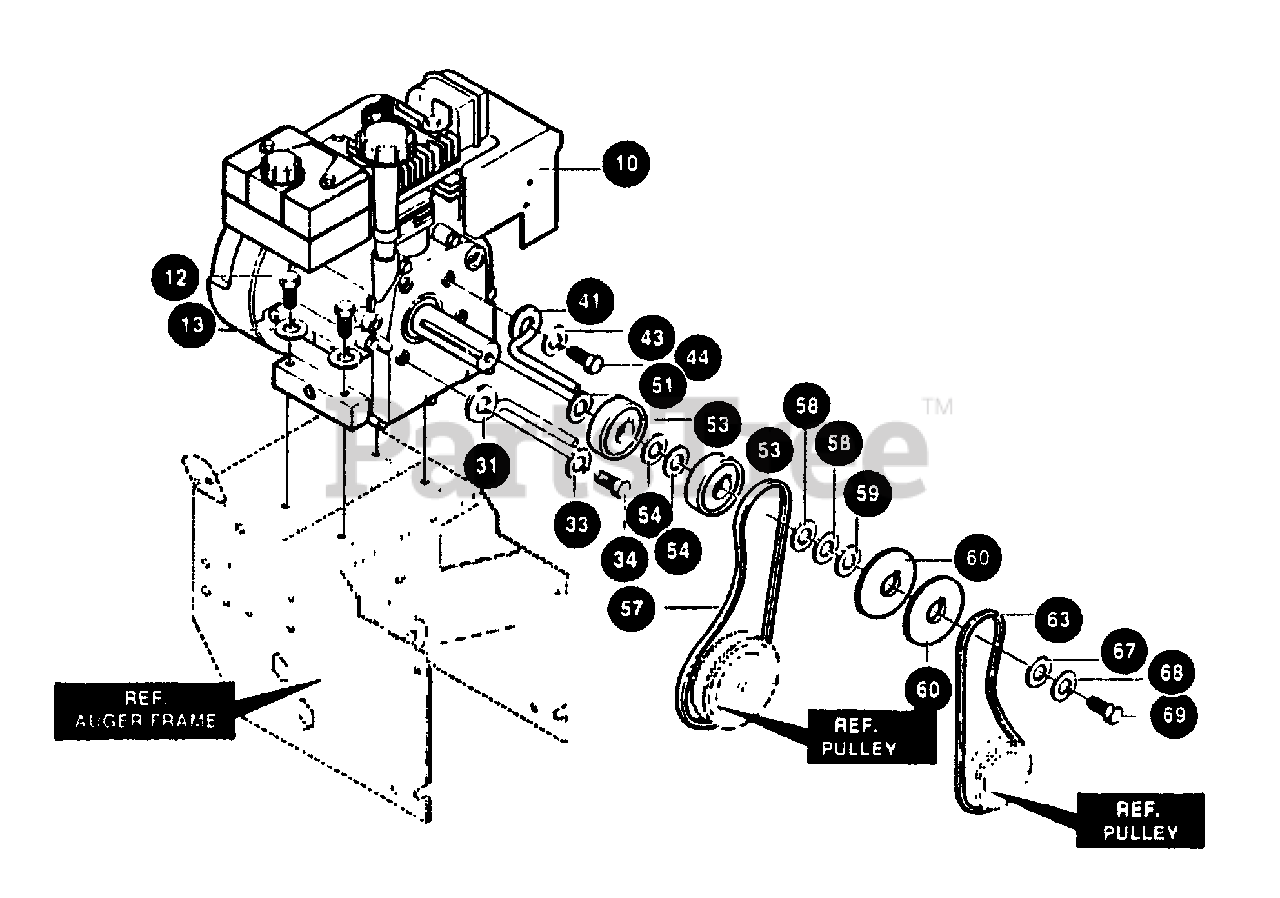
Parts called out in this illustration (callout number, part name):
12	SCREW 5/16-18X1.50
13	WASHER, .328X.60X.09
31	GUIDE, ROD BELT RH
33	WASHER,.328X.60X.09
34	SCREW, 5/16-24X 1.00
41	GUIDE, ROD BELT RH
43	WASHER, .328X.60X.09
44	SCREW, 5/16-24X 1.00
51	WASHER, CRANKSHAFT
53	PULLEY, HALF
54	FLATWASHER .752X.91 X.0
57	BELT. V 3L 33.13LG
58	FLATWASHER .765X 1.12X.06
59	SPACER, SLEEVE
60	PULLEY. ENGINE
63	BELT. V 4L 38.1 LG
67	WASHER, FLAT
68	WASHER, 393X.68X.10
69	SCREW, 3/8-24X1.00
